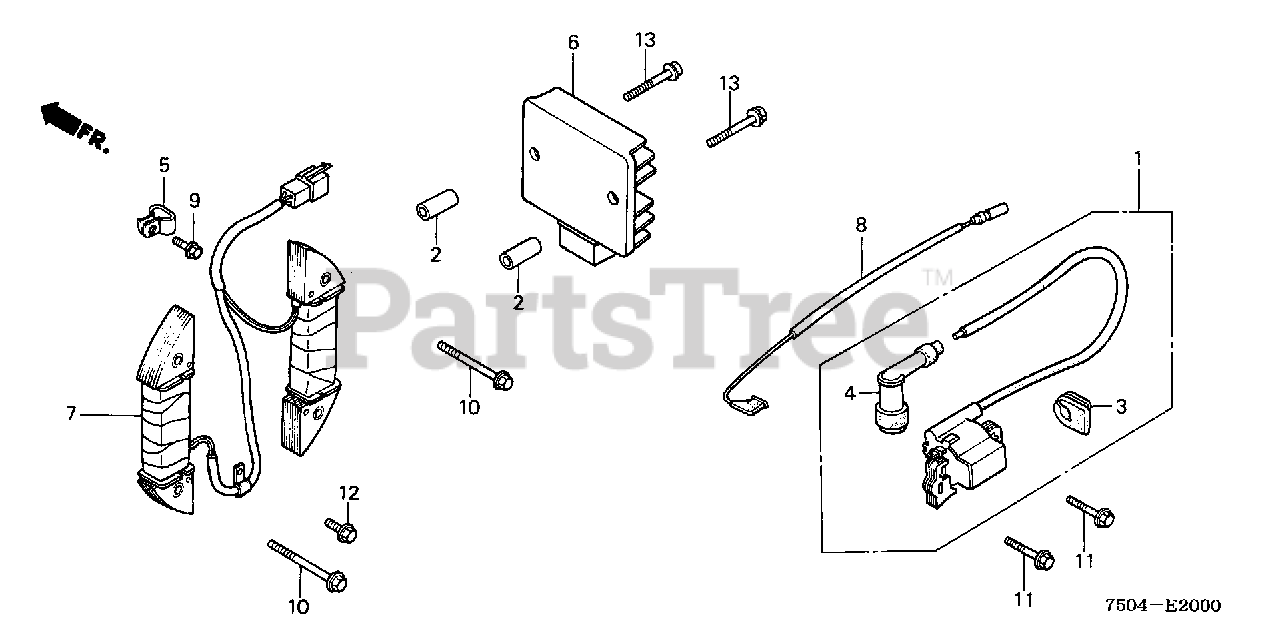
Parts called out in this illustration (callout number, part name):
1	COIL ASSY., IGNITION
2	COLLAR, IGNITION COIL SETTING
3	GROMMET, WIRE
4	CAP ASSY., NOISE SUPPRESSOR (NOT AVAILABLE)
5	CLAMP, IGNITION WIRE
6	RECTIFIER ASSY., REGULATOR
7	COIL ASSY., CHARGE
8	WIRE, STOP SWITCH
9	BOLT, FLANGE (6X12) (CT200)
10	BOLT, FLANGE (6X32)
11	BOLT, FLANGE (6X23)
12	BOLT, FLANGE (5X10)
13	BOLT, FLANGE (6X32)
13	BOLT, FLANGE (6X40)
